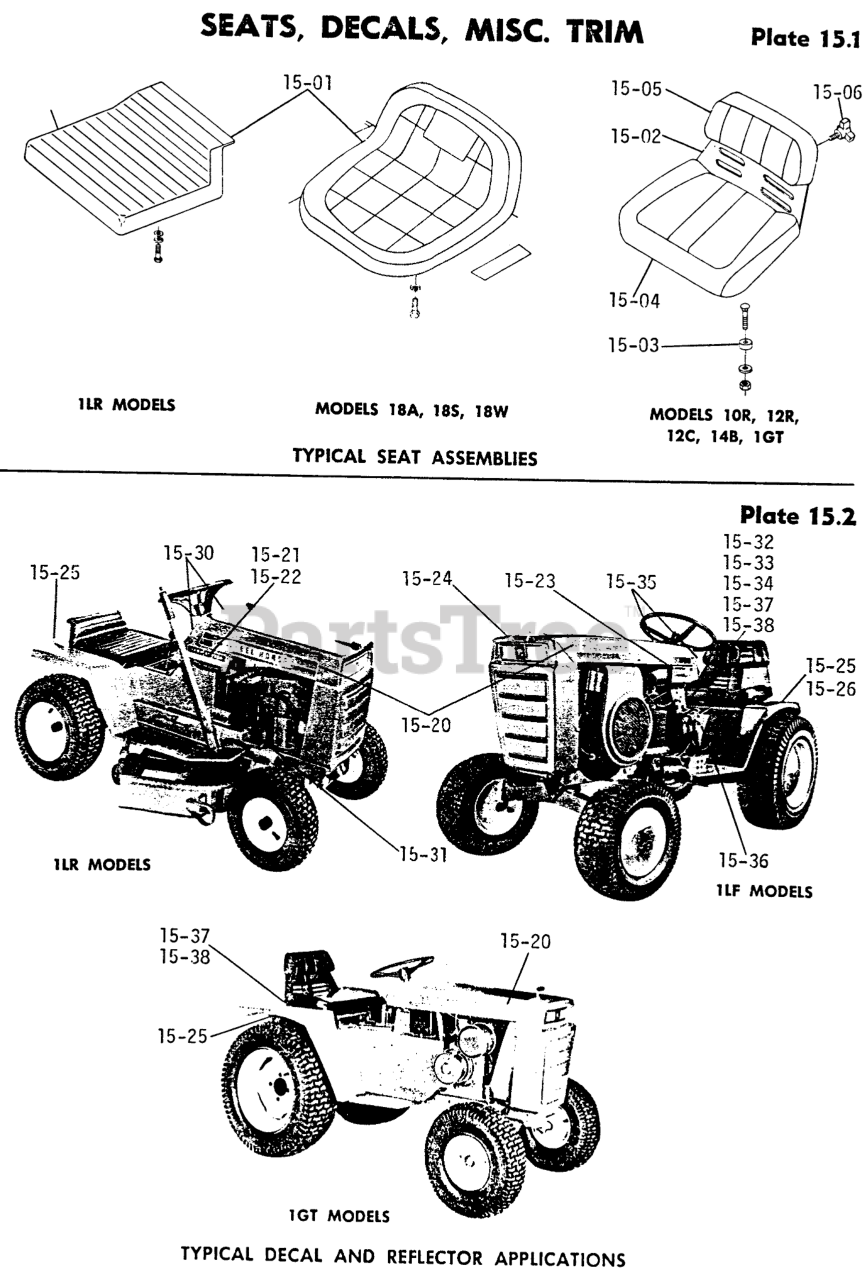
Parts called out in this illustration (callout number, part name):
15-01	Cushion-Seat
15-01	Screw 1/4-20 x 5/8
15-01	Washer
15-01	Lockwasher
15-01	Bolt Hex 5/16-18
15-03	Bolt-Car. 5/16-18 x 1
15-03	Nut, 5/16-18
15-03	Lockwasher
15-03	Nut 5/16-18
15-04	BULLT 281
15-04	Bolt, 1/4-20 Whizlock
15-05	BULLT 281
15-20	DECAL
15-20	ELBOW-45 DEG. ST, 1 1/4 BLK
15-20	Decal-Hood-L.H.
15-21	Decal-Lower Hood
15-22	Decal-Electric
15-23	Decal-800 3-Speed
15-23	Decal-800 Automatic
15-23	Decal-800 Special
15-23	Decal-Raider 10
15-23	Decal-Charger 12
15-26	Reflector
15-30	Decal-Hood R.H.
15-33	Decal Shift Pattern
15-35	Decal-Lift
15-36	Decal
15-37	Decal Free Wheeling
15-38	Decal
